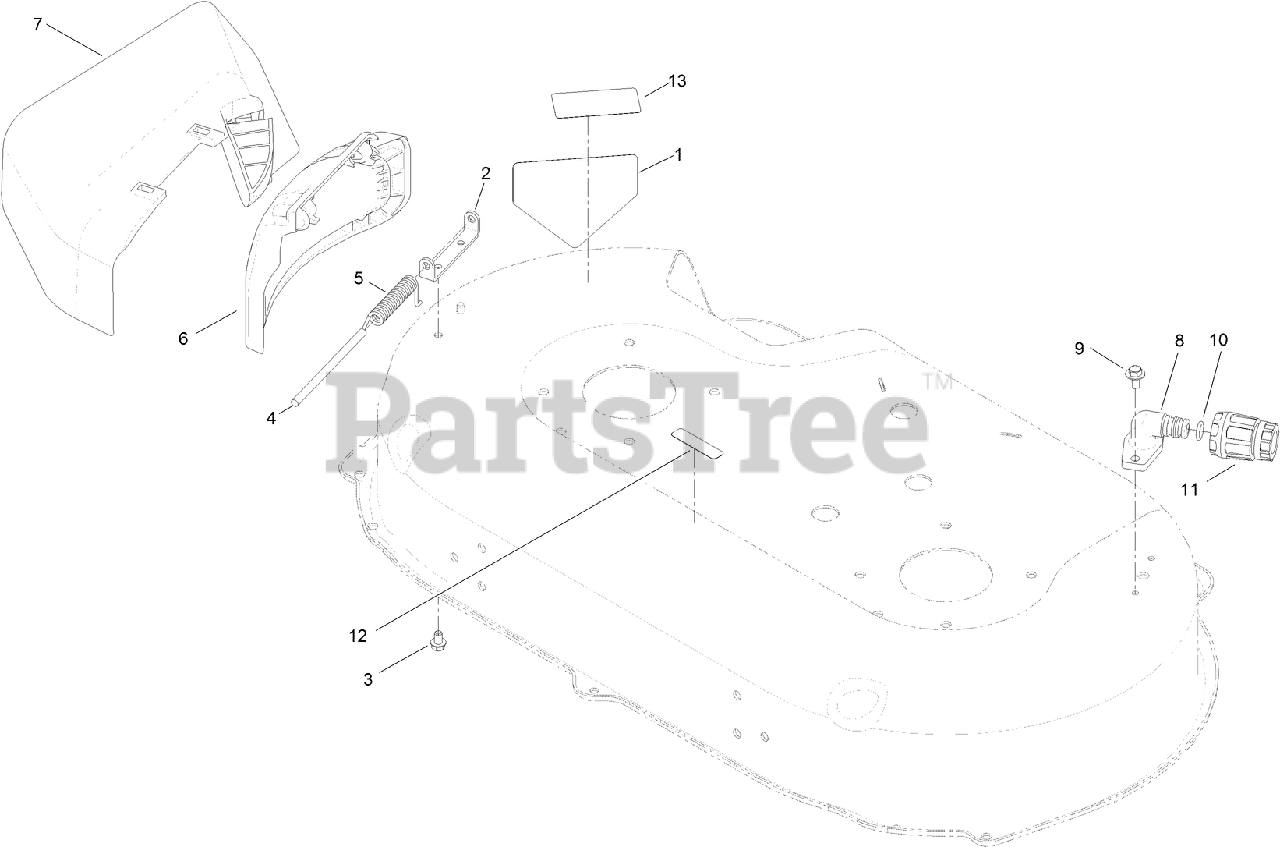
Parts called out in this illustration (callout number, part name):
1	DECAL-DANGER
2	BRACKET-COVER
3	SCREW-HWH
4	ROD-COVER
5	SPRING-TORSION, COVER
6	DEFLECTOR-SIDE
7	CHUTE-DISCHARGE, SIDE
8	FITTING-WASHOUT
9	SCREW-HHFTF
10	O-RING
11	CONNECTOR-HOSE
12	DECAL-WARNING
13	DECAL-PLACEMENT, FOOT
